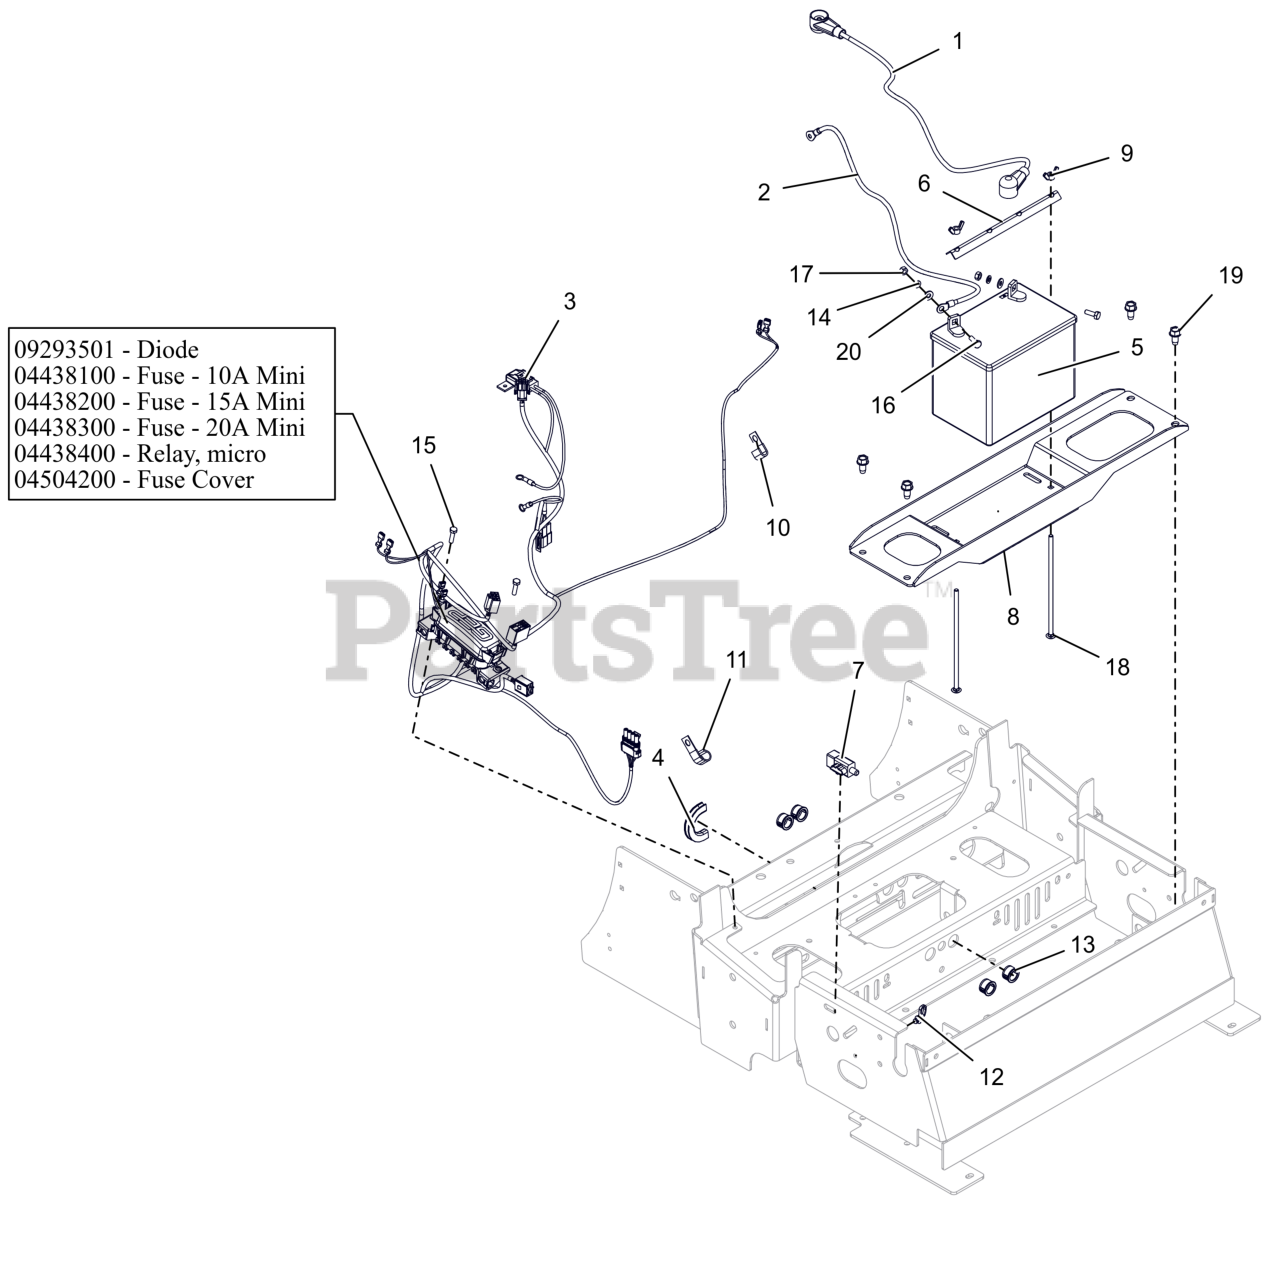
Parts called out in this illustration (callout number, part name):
1	CABLE - POS BATT W/BOOTS 6X35
2	CABLE-NEGATIVE BATTERY 35.00"
3	HARNESS, PT200/400 EFI WIRING
3	DIODE, CONNECTOR SHELL
3	FUSE,10 AMP MINI-ATC
3	FUSE,15 AMP MINI-ATC
3	FUSE,20 AMP MINI ATC
3	RELAY,MICRO5 TERML W/RESISTOR
3	COVER, HARNESS FUSE/RELAY MOD
4	STRIP, COWL
5	BATTERY, 300 CCA 10U1L
6	HOLD DOWN
7	SWITCH, SNAP IN - N.O./N.O.
8	PT200/400 BATTERY TRAY - RED
9	NUT, LK-WING .25-20 ZCC
12	CABLE TIE W/ TREE (.25 HOLE)
13	BUSH, PANEL SNAP .687X.875X.56
14	WSHR,LK-REG .250X.062 ZCC
15	BLT, HEX M6-1.0 X 25 G8.8 ZCC
16	BLT, HEX .25-20X.75 G5 ZCC
17	NUT-STD .250-20 G2 ZCC
18	BTL,RHSN .250-20 X 7.5 G5 ZCC
19	SCR,TAP .375-16X.75 HWH TR ZCC
20	WSHR,FLT .281X.625X.065 ZCC
